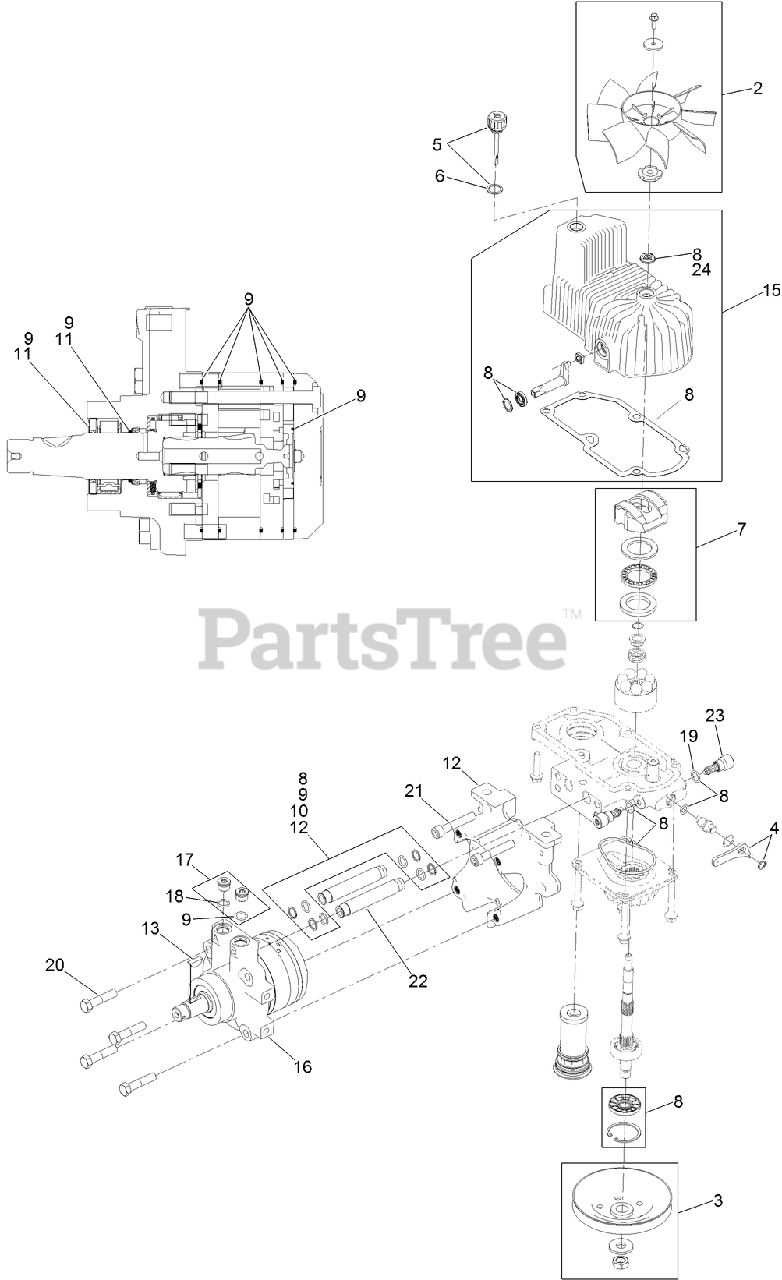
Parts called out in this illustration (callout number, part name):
2	FAN KIT
3	PULLEY KIT
4	HANDLE-BYPASS VALVE, HYDRO
5	DIPSTICK-HYDRO W/GASKET
6	GASKET-DIPSTICK, HYDRO
7	SWASH BLOCK KIT
8	PUMP SEAL KIT
9	MOTOR SEAL KIT
10	TUBE SEAL KIT
11	OUTPUT SHAFT SEAL KIT
12	NOSE CUP-UHT
13	KEY-WOODRUFF
15	Housing-LH
16	MOTOR-HYDRAULIC LH 240CC
17	MAGNETIC PLUGS SERVICE KIT
18	O-RING
19	O-RING-CHECK VALVE
20	SCREW HH
21	SCREW-HSH
22	HYDRAULIC TUBE KIT
23	SHOCK VALVE, 12CC HYDRO
24	SEAL-FAN DRIVE
